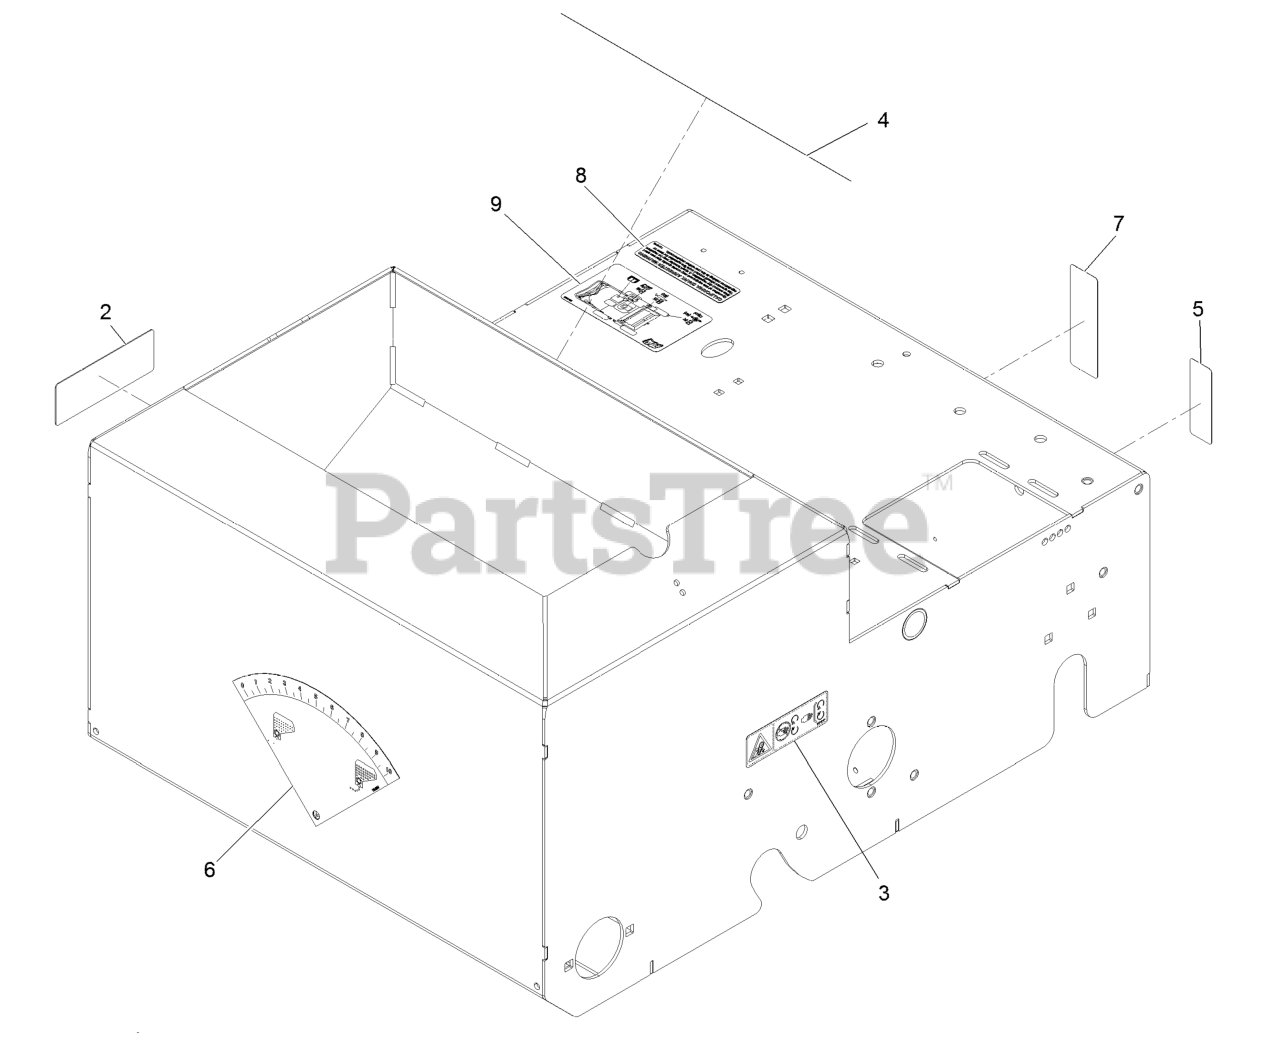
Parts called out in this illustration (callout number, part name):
2	DECAL-DANGER
3	DECAL-WARNING
4	DECAL-WARNING
5	DECAL-BRAKE, PARKING
6	DECAL-FLOW, SEED
7	DECAL-BYPASS
8	DECAL-ARRESTER, SPARK
9	Decal-Service Aid Seeder
